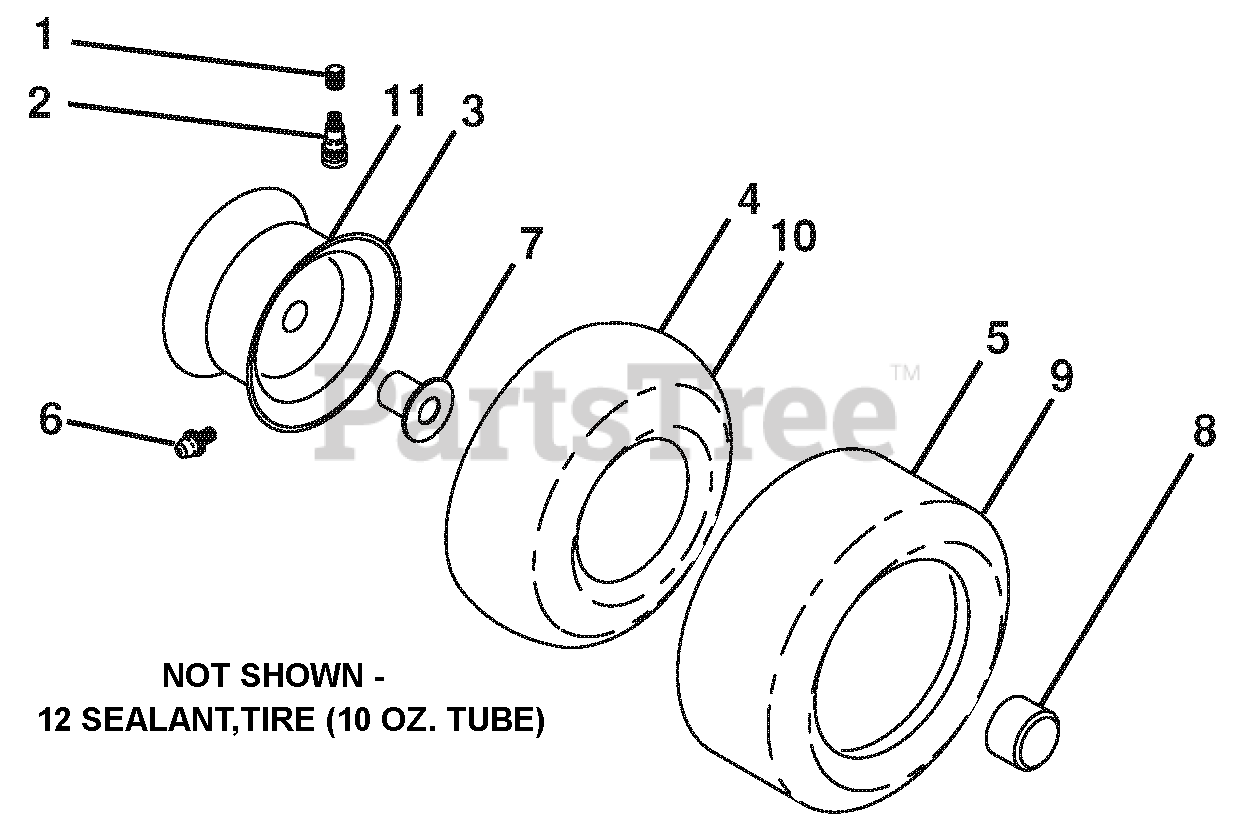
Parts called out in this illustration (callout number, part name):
1	CAP.VALVE.TIRE
2	STEM.VALVE
3	RIM.ASM.6"FRONT
4	TUBE.INNER.FRONT.#35060
5	TIRE.F.TS.15 X 6.0 - 6.SERVICE
6	FITTING, GREASE
7	BEARING FLANGE
8	CAP AXLE (FRONT WHEEL ONLY)
9	TIRE.R.TS.20 X 8-8.C.SERVICE
10	TUBE, REAR
11	RIM.ASM.8"REAR
